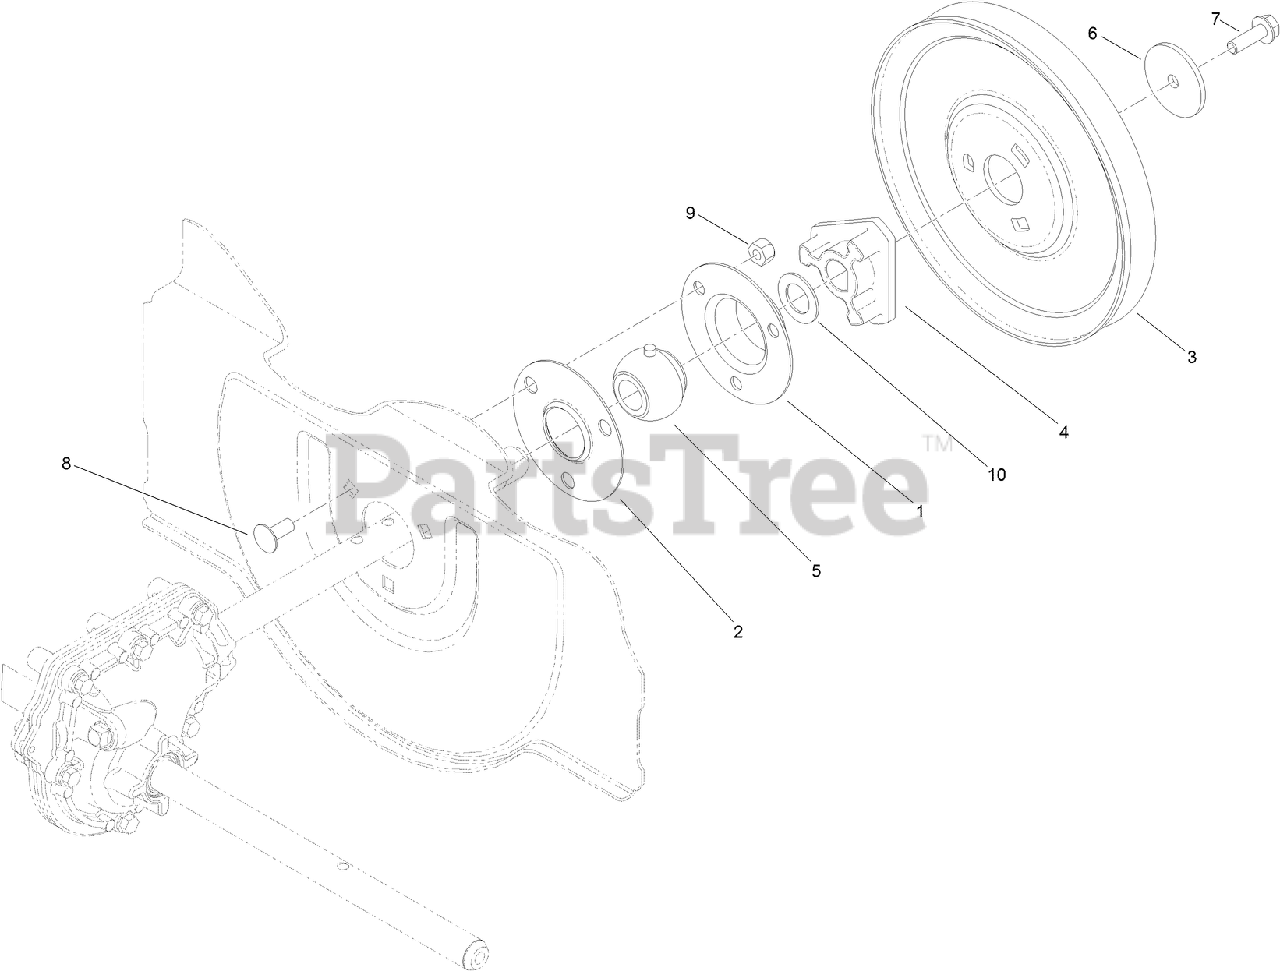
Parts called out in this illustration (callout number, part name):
1	FLANGE-CUP, BEARING
2	FLANGE-CUP, BEARING
4	HUB-IMPELLER, PULLEY
5	BEARING
6	WASHER-PLAIN
7	SCREW-HHF
8	SCREW-CARR
9	NUT-LOCK, NI
10	WASHER-THRUST
